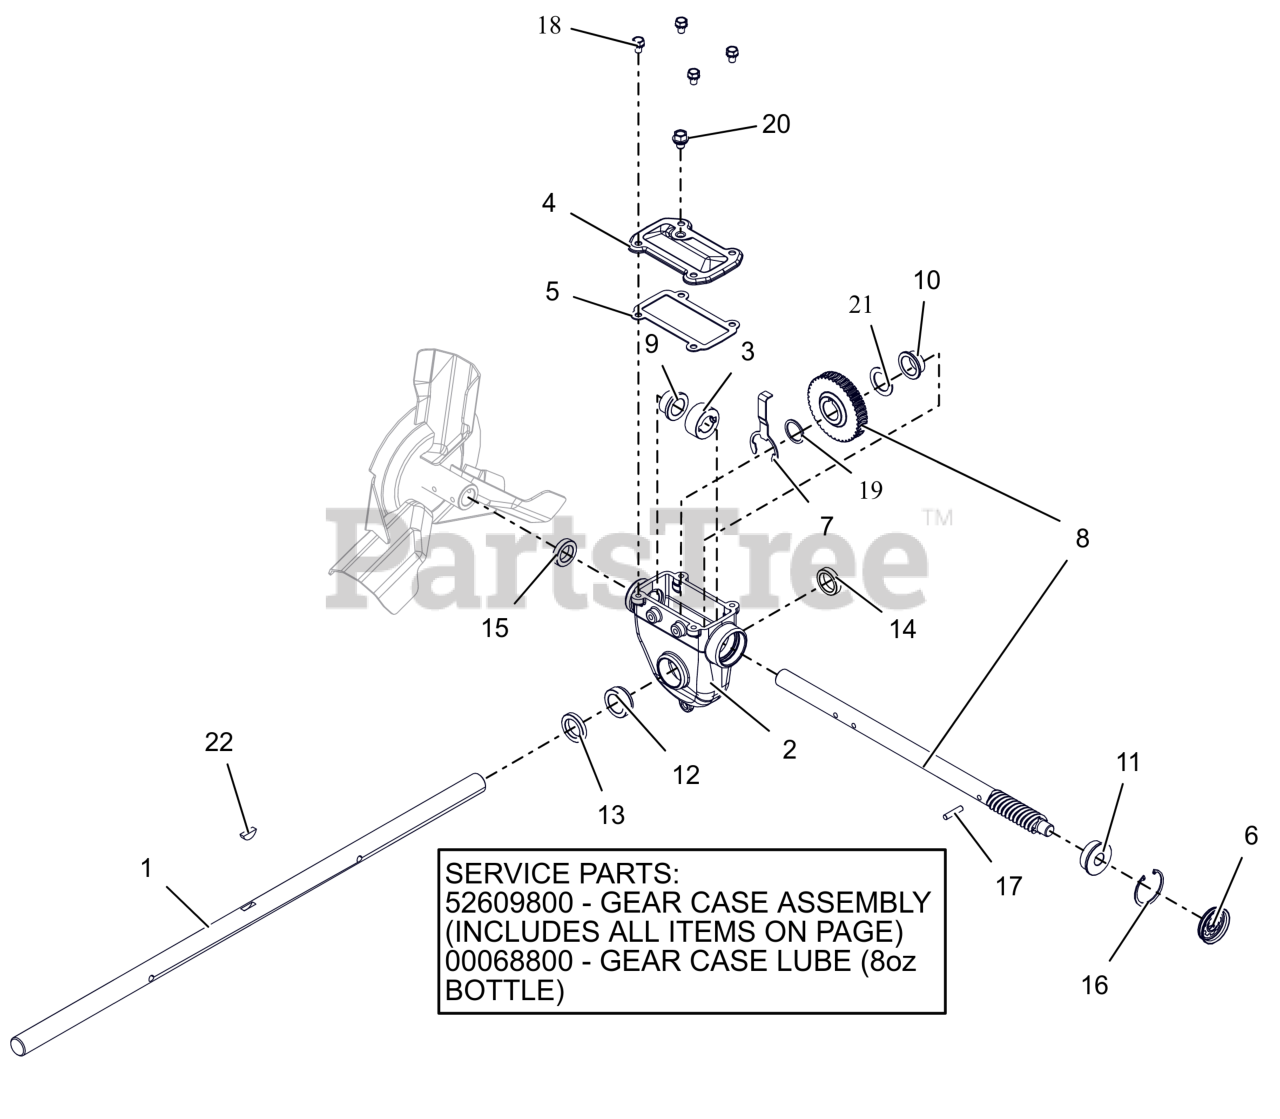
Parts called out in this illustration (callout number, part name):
1	SHAFT, RAKE-32"
2	GEARCASE, LARGE MACHINED
2	ARIENS L3 LUBE, 8 OZ BOTTLE
3	THRUST COLLAR, .875"ID SLIPFIT
4	COVER, TOP - LARGE IRON
5	GASKET, TOP - LARGE GEARCASE
6	COVER, GEAR CASE 1.75"
7	BUSHING RETAINER, LARGE
8	ASSY, WORM SHAFT & GEAR
9	BSHG-FLG .879X1.128X.75X1.45
10	BSHG-FLG 1.006X1.128X.555X1.45
11	BSHG-FLG .628X1.503X.58X1.725
12	BSHG-FLG LARGE, RIGHT
13	SEAL-OIL .999X1.500X.250 TBC29
14	SEAL-OIL .999X1.375X.312 TBC29
15	SEAL-OIL .873X1.375X.312 TBC29
16	RG-RTNG-INT 1.750X.062
17	PIN-STR .250X1.12 6150
18	BLT, SEMS .31-18X.50 G5 ZCC
19	WSHR, FLT 1.010X1.250X.068 ZCC
20	SCR, .380-15X.500 W/SEAL WASHER
21	WSHR, FLT 1.010X1.505X.062 ZCC
22	KEY-WDRF .25X.875 HRD #A
